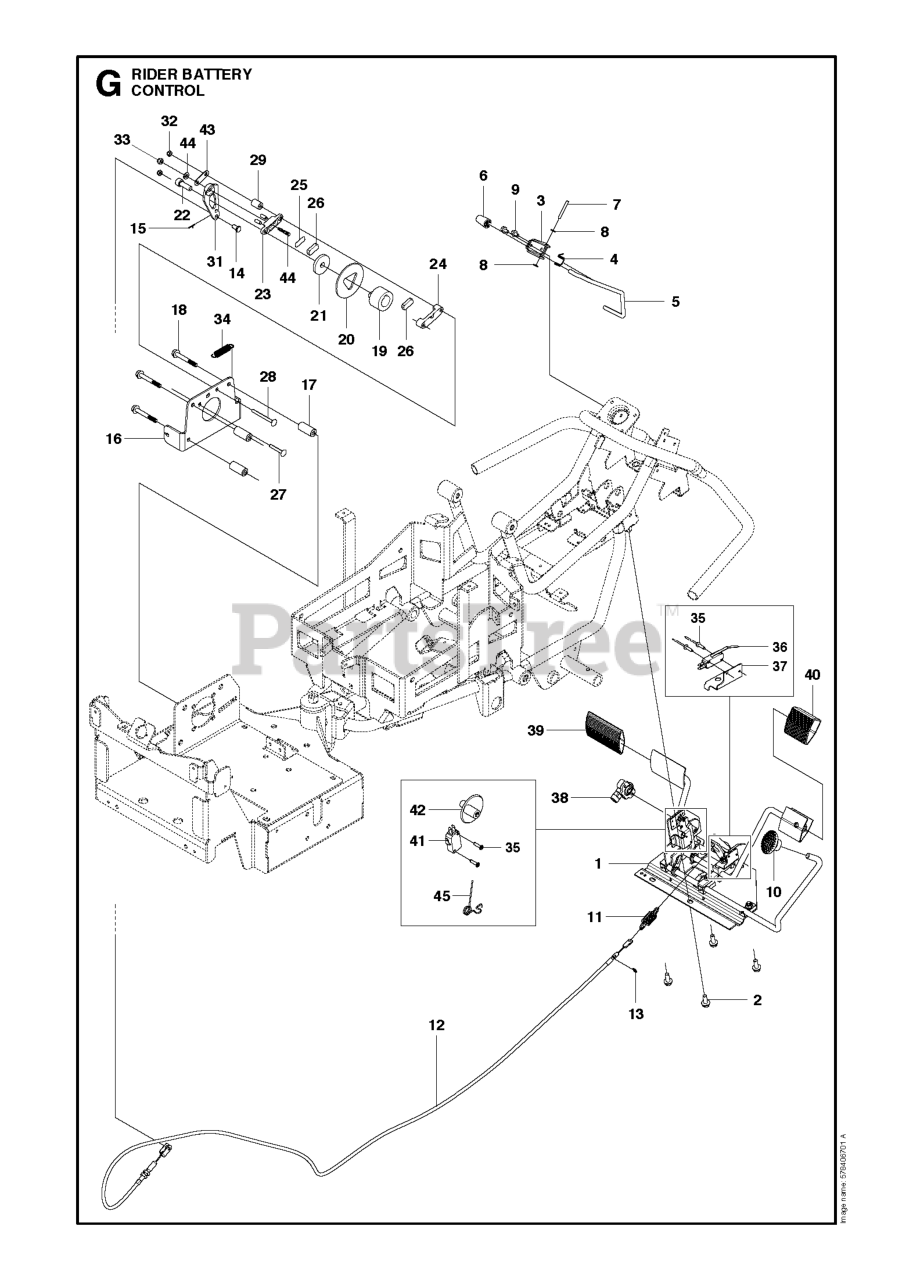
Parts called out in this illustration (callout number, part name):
10	KNOB
14	Clevis Pin
15	Cotter Pin
21	SPINDLE WASHER
22	SCREW IHSCM M10X30 12.9 ZPB L
32	LOCKNUT M6
36	MICRO SWITCH
39	PEDAL RUBBER, SF
40	PEDAL RUBBER
41	%BRAKER
43	WASHER - 26X6.5X1.6
